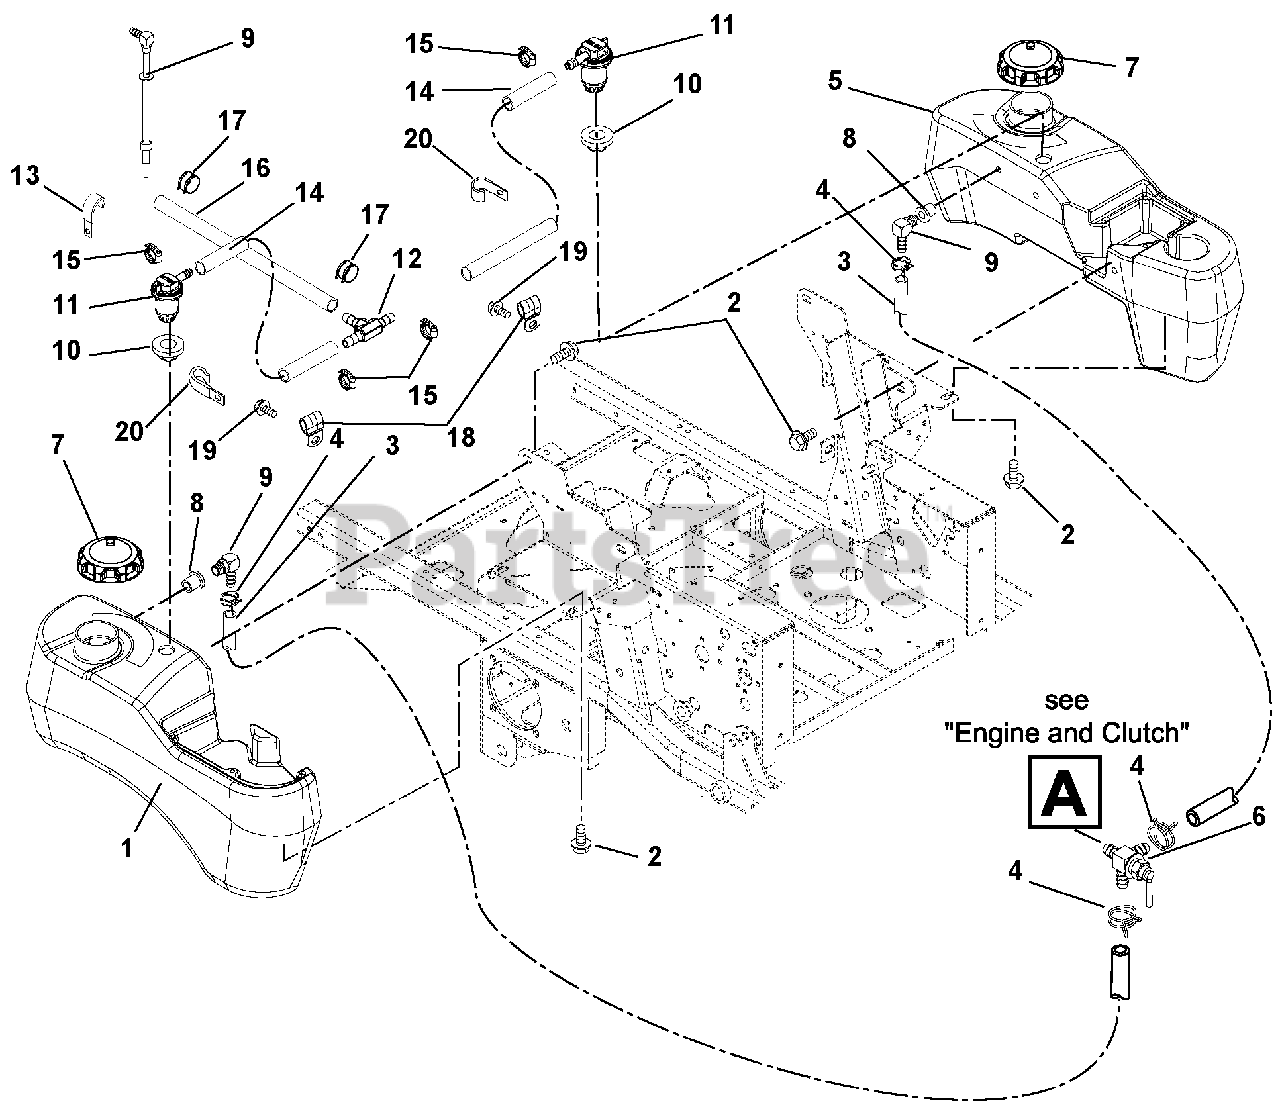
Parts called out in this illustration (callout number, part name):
1	Tank, Fuel Right Hand
2	Bolt, SEMS .31-18 x .62
3	Hose, .25 Low-PERM Bulk Gas (3 @ 42")
4	Clamp, Fuel Line
5	Tank, Fuel Left Hand
6	Valve, Fuel
7	Cap, Fuel Vent-in Autolock
9	Assembly, Large Tank Fuel Pick-up
10	Grommet, Remote Vent Nitrile
11	Valve, Combination
12	Fuel Tee, .25 HS Run x .18 HS Branch
14	Hose, .25 Low-PERM Bulk Gas
15	Clamp, Fuel Line
16	Hose, .188 Low-PERM Bulk Gas
17	Clamp, Hose Spring .188
18	Clamp, Cushioned Steel
19	Screw, Tapping Hex Washer Head Thread Rolling .31-18 x .50
